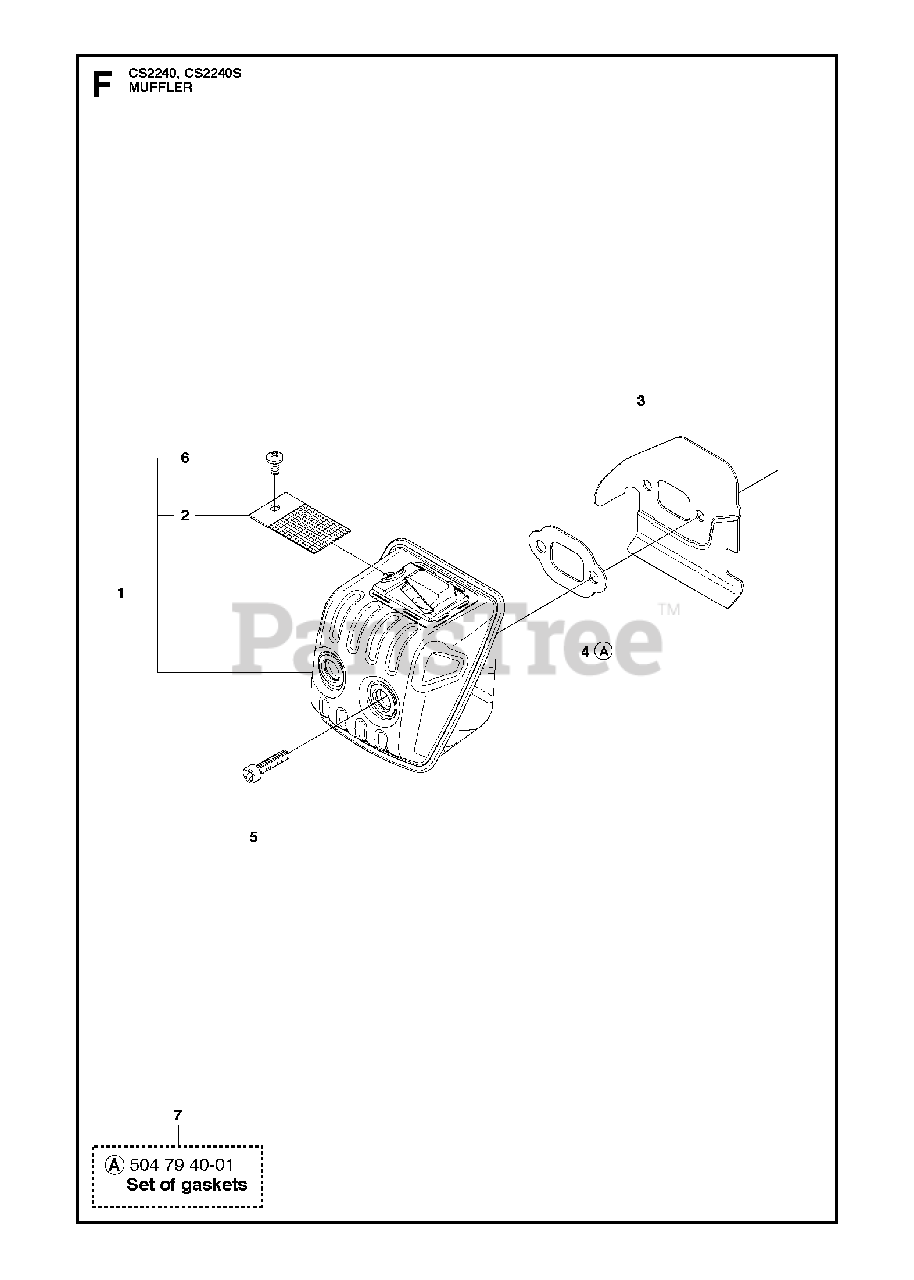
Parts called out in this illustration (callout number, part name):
1	MUFFLER ASSY
2	RP SCREEN
3	HEAT DEFLECTOR
4	GASKET
5	SCREW MC6S 6X16
6	SCREW
7	GASKET SET
